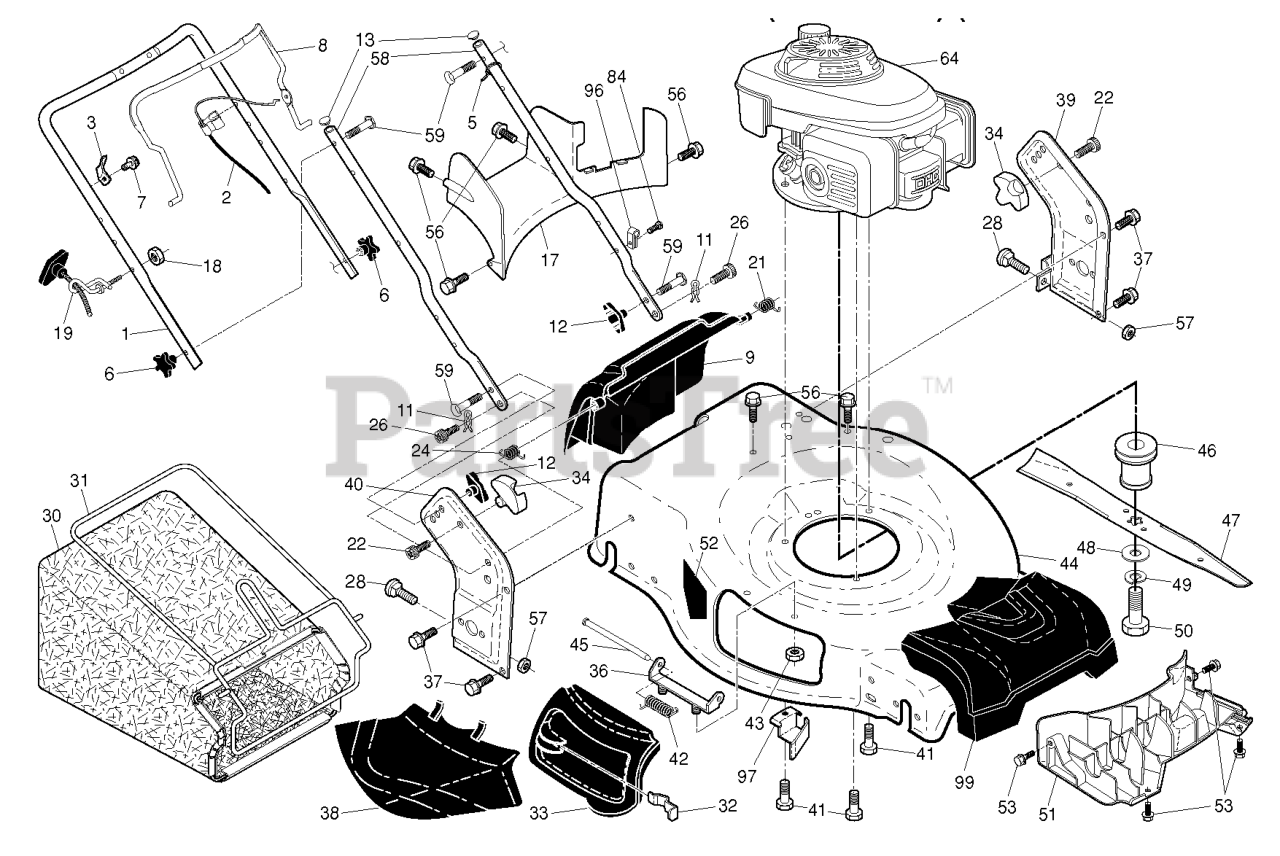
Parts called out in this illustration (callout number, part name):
1	HANDLE.UPPER.3.POS.BS.AW2.GREY
2	CABLE.MZR.50.SNAP-IN
3	BRACKET.UPSTOP.RT
5	TIE GUIDE
6	KNOB.HANDLE.PLASTIC.STAR.BLACK
8	BAIL.OVER.MOLD.ERGO.MZR.ORANGE
9	DOOR.REAR.ASM.22+.HUSQ.F/RG.CE
11	COTTER.HAIRPIN.DOOR/HANDLE.PIV
12	KNOB, DEFLECTOR
13	PLUG.PLASTIC.7/8".14-20.GAUGE
17	RP.BAFFLE.REAR.22+.RGD.PL
18	NUT
19	RB GUIDE.ROPE.STD.BLK.ZIN WSL
21	SPRING.LH.BLACK
22	SCREW.PAN.HEAD.#10
24	SPRING.RH.GRAY
26	SCREW,DOOR/HANDLE.PIVOT
28	BOLT
30	GBAG.BA85028ER.GRY/ORG
31	RB FRAME.GBAG.22PLUS
32	LATCH.DOOR.ZINC
33	DOOR.MULCH.22 PLUS.HUSQ.GREY
34	BRACKET.GRASSBAG.ATTACHING.BLK
36	BRACKET.ASM.HINGE.21.FWGD.
37	BOLT.5/16HEX.WHS.HD
38	DEFLECTOR.CLIPPING.22.BLACK
39	BRACKET.ASM.HNDL.LT.22+.GREY
40	BRACKET.ASM.HNDL.RT.22+.GREY
41	BOLT 3/8-16X1-1/8
42	SPRING.TORSION
43	NUT.HEX.FLANGE.1/4
44	HOUSING.22.FGD.MC.WO.HD.ORN.CE
45	ROD.HINGE.21
46	ADAPTER.BLADE.25MM.3MPH
47	BLADE.22+4N1.2PIN.5STAR.(P07)
48	WASHER,HARDEN
49	LOCKWASHER
50	SCREW, HEX HD 3/8-24 X 1-3/8
51	BAFFLE.FRONT.22+PLASTIC.(2 2)
52	DANGER DECAL
53	SCREW.HI-LO.5/16 X.75
56	SCREW.HX.13X.750
57	NUT.FLANGE.5/16
58	HANDLE.LOWER.22+BT.2PC.GRY
59	BOLT, HANDLE 5/16-18X1.75
84	FASTENER.PUSH.O.250X0.783
96	CLIP.CABLE.BLK
97	BRACKET.BELT.GUIDE.22+.BZP
99	COVER.ASM.FRONT.SHROUD.HUSQ.
